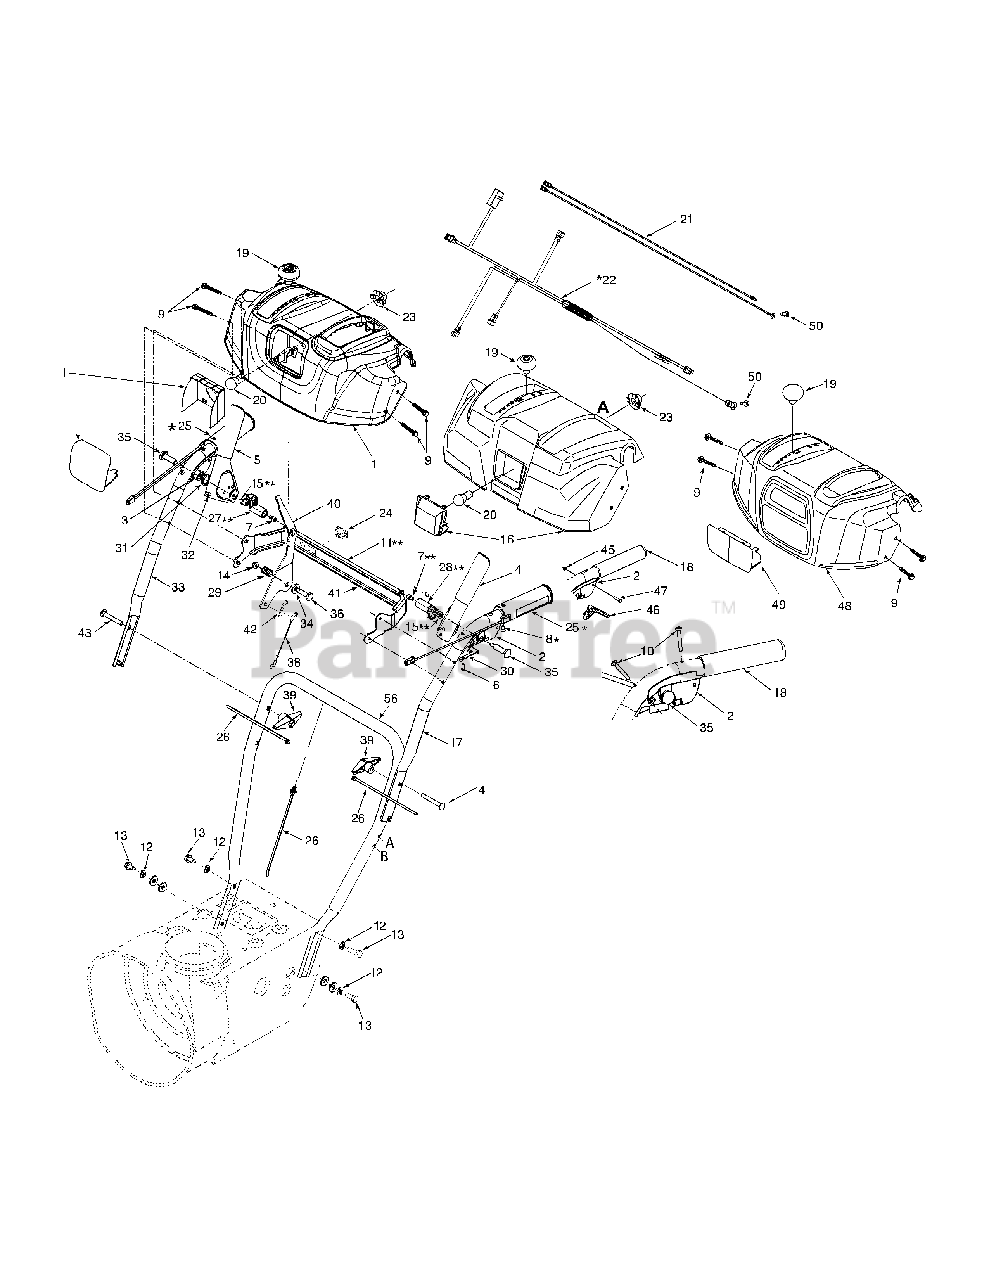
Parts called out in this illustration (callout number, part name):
1	Handle Panel Ass’y-Black w/Chute Control
2	LH Clutch Lock Handle Ass’y
3	RH Clutch Lock Handle Ass’y
4	Engagement Handle Assembly LH - Black
5	Engagement Handle Assembly RH - Black
6	Screw #8-16 x .50
7	Hex Cap Socket Screw 1/4-20 x .5
8	Oval HD C-Sunk Scr #10 x 5/8
9	Hex TT-Tap Scr 1/4-20 x 1.625
10	Oval C-Sunk Hd Screw 10-24 x 1.375
12	Lockwasher 5/16 ID
13	Hex TT Screw 5/16-18 x .75 Gr. 5 Patch
14	Hex L-Flanged Nut 1/4-20 Gr. F Nylon
15	Hex Shoulder Nut 1/4-20
15	Hex L-Flg Nut 1/4-20 Gr. F Nylon
16	Handle Panel Ass’y
20	Lamp
22	Heated Grip Wire Harness
23	Socket
26	Cable Tie (w/plug)
26	Cable Tie (w/heated grips)
28	Clutch Lock Cam
29	Compression Spring .38 ID x .88 Lg
30	Spring: Clutch Lock
31	Torsion Spring .8156 x .3038
32	Rubber Bumper
34	Flat Washer .38 ID x .87 OD x .09
35	Shoulder Screw .437 x 1.345: 1/4-20
36	Shoulder Screw .374 Dia. x 1.05 Lg.
37	Flat Washer .344 ID x .688 OD x .065
38	Selector Speed Cable
39	Handle Knob Assembly
41	Panel Support
42	Cotter Pin
43	Carriage Bolt 5/16-18 x 2.25
46	Steering Control - Black
46	Steering Control - Yellow
48	Handle Panel Ass’y - Red (w/lens)
50	Hex Wash S-Tapp Scr 1/4-20 x .50
